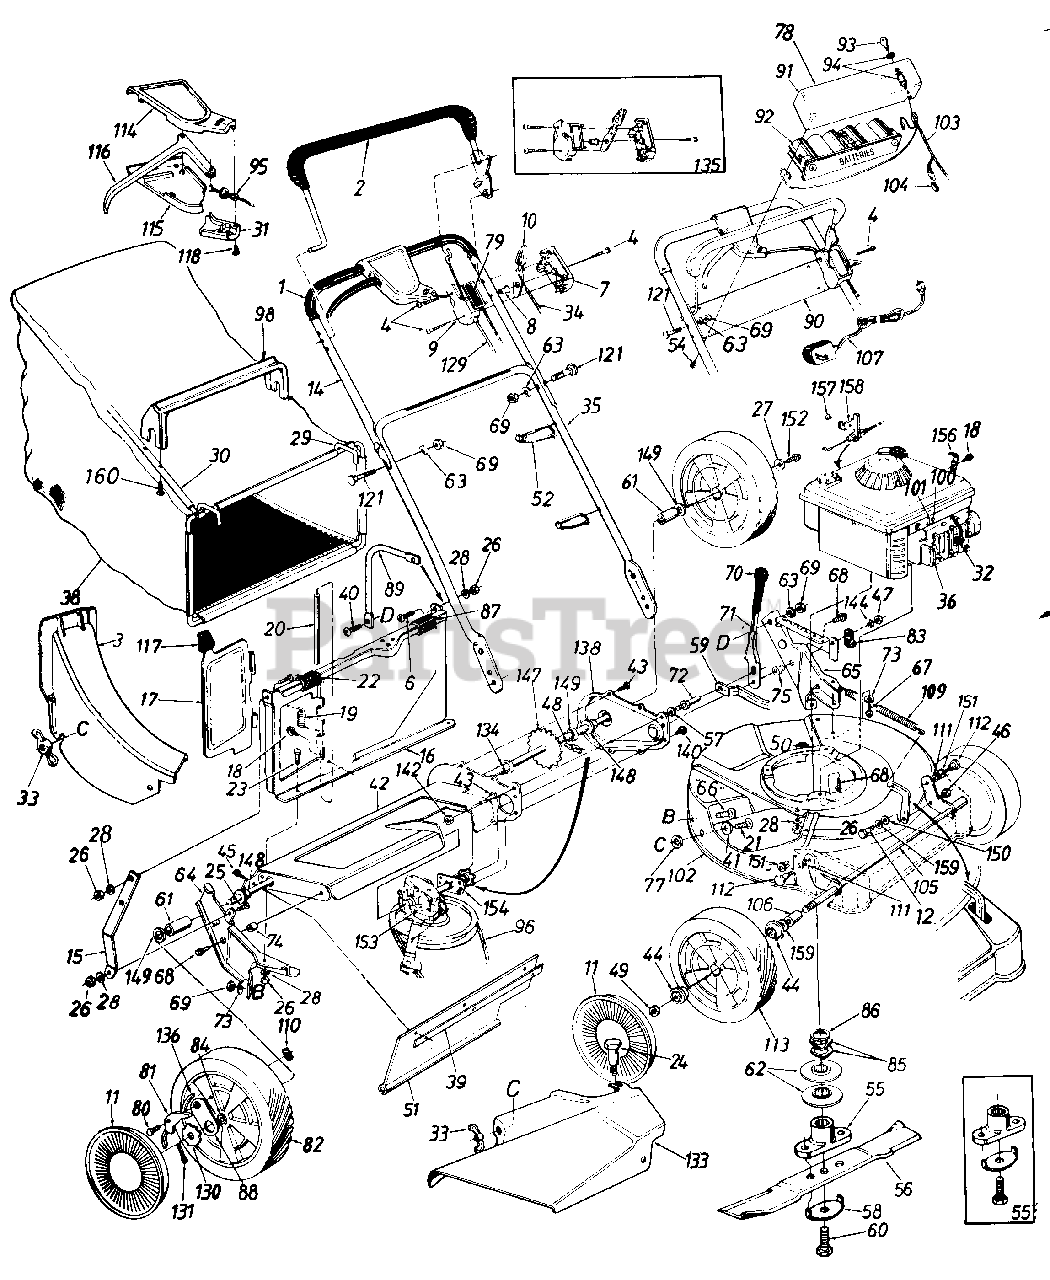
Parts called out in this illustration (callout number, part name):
1	Foam Grip
2	Control Handle Ass'y.-L.H.
3	Top Discharge Chute Ass'y.
4	Truss Mach. Scr. #12 x 1.50" Lg.
6	Truss Mach. Scr. 1/4-20 x .62" Lg.
7	Control Panel Half
8	Control Disc Pin
9	Clutch Panel Half
10	Throttle Control Lever
11	Hub Cap (Radial)
12	Shld. Bolt .5" Dia.
14	Upper Handle-Painted
18	Hex B-Tap Scr. #10 x .38"
19	Torsion Spring
20	Pivot Pin
21	Carriage Bolt 1/4-20 x .62"
22	Truss Mach. Scr. 1/4-20 x 3/4" Lg
23	Hex Bolt 1/4-20 x .50" Lg.
24	Shoulder Bolt .312 Dia. x .18 Lg.-Special
25	Hex Bolt 1/4-20 x .62" Lg.
26	Hex Nut 1/4-20 Thd.
27	Bell-Wash. 1/4" I.D.
28	L-Wash. 1/4" I.D.
31	S.P. Control Cover
32	Spark Plug Insulator
33	Wing Nut w/Washer
34	Throttle Control Wire 58"
35	Lower Handle-Painted
36	Engine
38	21" Top Discharge Grass Bag-Black
39	Retaining Strip
40	Truss Mach. Scr. 5/16-18 x .75" Lg.
41	Fl-Wash. .344" I.D. x .62"
44	Flange Ball Bearing 1/2" I.D.
45	Hex AB-Tap Scr. 1/4 x .62"
46	Hex Jam Nut 3/8-16 Thd.
47	Hex Patch L-Nut 3/8-24 Thd.
48	#48 Chain .500" Pitch x 30 Links
49	Hex L-Nut 1/2-20 Thd.
51	Rear Flap 3.75" x 17.30" Lg.
52	Cable Tie
54	Hex AB-Tap Scr. 1.0" Lg.
55	Blade Adapter Kit
56	21" Blade
57	L-Wash. 3/8" I.D.
58	Blade Bell-Wash. .44" I.D. x 2.38"
59	Height Adj. Rod 19.42" Lg.
60	Hex Bolt 7/16-20 x 1.5" Lg. (Grade 5)
61	Spacer .513" I.D. x .703" O.D. x .69" Lg.
62	Serrated Pulley Half
63	L-Wash. 5/16 I.D. ,
64	R.H. Handle Wheel Brkt. Ass'y.
65	L.H. Handle Wheel Brkt. Ass'y.
66	Carriage Bolt 5/16-18 x .62"
67	Hex Wash. Hd. B-Tap Scr. 5/1 6-1 8
68	Hex Wash. Hd. TT-Tap Scr. 3/8-1 6
69	Hex Nut 5/16-18 Thd.
71	Height Adj. Lever
72	Shld. Pin 3/8-24 x 1.43" Lg.
73	Bell-Wash. 5/16" I.D.
74	Spacer.383" I.D.
75	Shld. Spacer. 500" Dia.
77	Bolt Retainer 1/4 x .50" O.D.
78	Instruction Label
79	Control Label
80	Shld. Scr. .342" Dia. x .268
81	Pawl
82	Wheel Ass'y. Comp.
83	Clamp
84	Bearing 1/2" I.D.
85	Wave Washer 1.005" I.D.
86	Serrated Washer 1.0" I.D.
87	Panel Clip
88	Pawl Plate
89	Catcher Panel Support Arm
90	Lower Battery Tray
91	Upper Battery Tray
92	12 Volt Battery
93	Key
94	Key Switch
95	S.P. Cable x 48" Lg.
96	"V"-Belt
98	Bag Handle (Black)
100	Hex B-Tap Scr. #10 x .62"
101	Cable Clamp
102	21" Deck Ass'y.
103	Wire Harness
104	Plug
105	Front Axle Ass'y.
106	Sleeve .526" I.D. x .690" O.D. x .880" Lg.
107	Battery Charger
109	Extension Spring .75" O.D. x 8.0" Lg.
110	Flat Weld Nut 1/4-20 Thd.
111	Intern. L-Wash. 3/8 I.D.
112	Shld. Bolt .575" Dia. x .42
113	Wheel Ass'y. Comp.
114	Self-Propelled Control Cover
115	Self-Propelled Control Cover
116	Control Lever
117	Door Grip
118	Fl-"C"-Sunk Hd. Tap Scr. #10 x .75" Lg.
121	Curved Carr. Bolt 5/16-18 x 1.38" Lg.
129	Control Cable 46" Lg.
130	Ratchet Wheel 1.62" O.D.
131	Cotter Pin 1/8" Dia. x 1.00" Lg.
133	Side Chute Deflector Ass'y.
134	Hex Flange Bearing
135	Kit-Control Housing Comp.
136	Spring-Nylon
142	Hex Jam Nut 3/8-24 Thd.
144	Fl-Wash. .385" I.D. x .87"
147	Rear Shaft Ass'y. 21.94" Lg.
148	Hex Flange Bearing .506" I.D. Plastic
149	Fl-Wash. .531" I.D. x .930"
150	Bell-Wash. .515" I.D. x 1.0" O.D.
151	Flanged Nyliner Brg.
152	Hex Bolt 1/4-20 x .62" Lg. (Grade 5)
153	Transmission Comp.
154	Hex Bearing Cup
156	Cable Clamp
157	Pop Rivet .156" Dia.
158	Cable Bracket
159	Fl-Wash. .51" I.D. x .75" O.D.
160	Hex AB-Tap Scr. 1.25" Lg.
